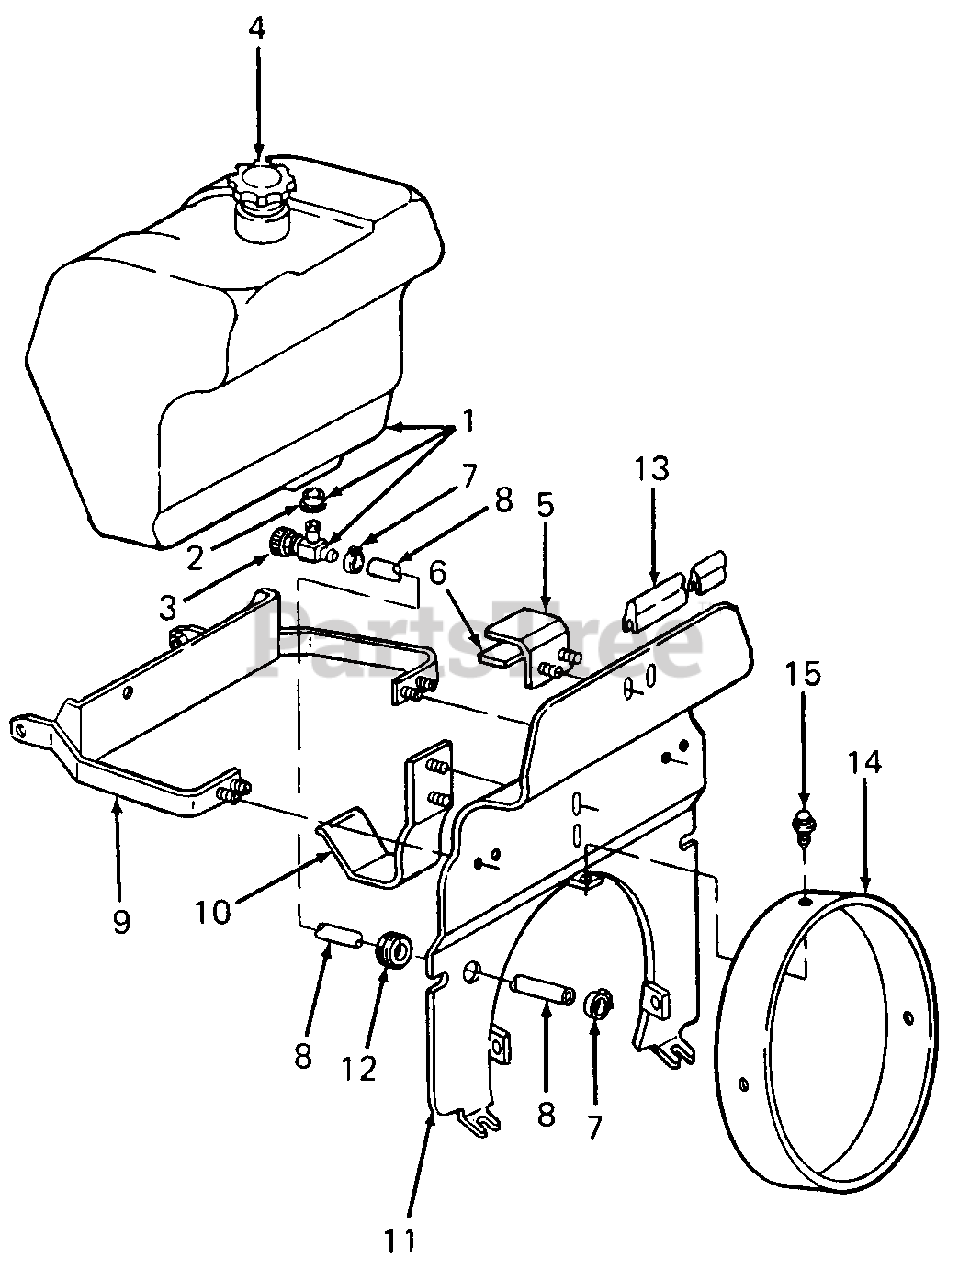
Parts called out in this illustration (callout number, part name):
1	Tank, Fuel
2	Bushing
3	Valve, Shutoff w/Screen
4	Gauge, Fuel Cap
5	Clamp, Fuel Tank
6	Pad, Fuel Tank Adhesive, Loctite #495
7	Clamp, Hose
8	Line, Fuel -14 in. Lg
9	Support, Fuel Tank
10	Support, Fuel Tank Bottom
11	Deflector, Heat
13	Seal, Heat Baffle, 56 in Lg
14	Shroud, Blower
15	Screw, Hex Wash Hd AB Tapp, #10 X .50 Lg
